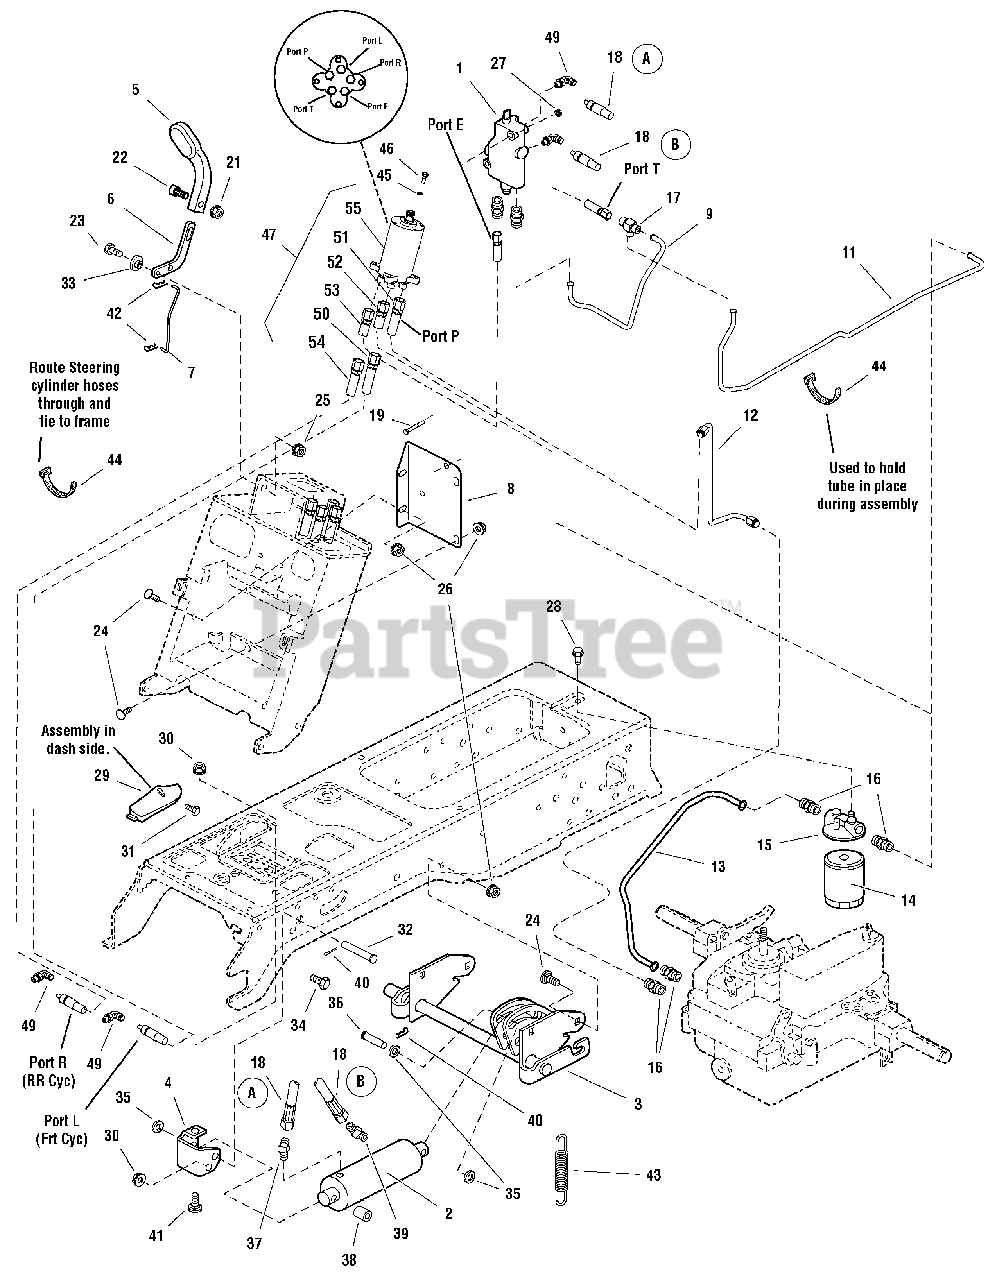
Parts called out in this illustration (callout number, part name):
1	VALVE, Control
2	CYLINDER, Hydraulic
3	SHAFT ASSEMBLY, Lift
4	SUPPORT, Cylinder
5	HANDLE, Lift
6	LEVER, Hydraulic
7	ROD, Curved Link
8	SUPPORT, Control
9	TUBE, Hydraulic
11	TUBE, Hydraulic
12	TUBE, Hydraulic 3 Bends
13	TUBE, Hydraulic
14	FILTER, Oil
15	BASE, Oil Filter
16	FITTING, Straight
17	FITTING, Tee, 3 Ports / Hydraulic Hose
18	HOSE ASSEMBLY, Hydraulic
19	CAPSCREW, Hex Head, 1/4-20 x 2 G5
21	NUT, Hex Lock ESNA Light 1/4-20
22	SCREW, Torx Plus Socket Head 1/4-20 x 7/8
23	CAPSCREW, Hex Head 5/16-18 x 1 G5
24	CARRIAGE BOLT, 5/16-18 x 3/4 G5
25	NUT, Hex Lock ESNA Light 5/16-18
26	NUT, Hex KEPS 5/16-18
27	NUT, Hex KEPS 1/4-20
28	SCREW, Hex Whiz Lock Flange, 1/4-20 x 1/2
29	COVER, Dash ABS
30	NUT, Hex KEPS 3/8-16
31	SCREW, Pan Head Torque, #8-16 x 1/2, Plastite
32	PIN, Clevis
33	SPACER, Hydraulic Lift Pivot
34	CAPSCREW, Hex Head 3/8-16 x 1 G5
35	WASHER, 1/2
36	PIN, Flat Head Drilled
37	FITTING, Elbow 1/2
39	FITTING, Elbow 1/2
40	CLIP, Hair Pin
41	CARRIAGE BOLT, 3/8-16 x 1 G5
42	PIN, Cotter 5/8 x 3/4
43	SPRING, Extension
44	TIE, Self Locking
45	LOCKWASHER, Spring 1/4
46	CAPSCREW, Hex Head
47	POWER STEERING ASSEMBLY, 32CC, 5 Ports
49	FITTING, Hose Elbow Perma Push 9/16-18
50	HOSE ASSEMBLY, 31"
51	HOSE ASSEMBLY, 27"
52	HOSE ASSEMBLY, 18"
53	HOSE ASSEMBLY, 20"
54	HOSE ASSEMBLY, 27"
55	POWER STEERING UNIT, 32CC, 5 Ports
